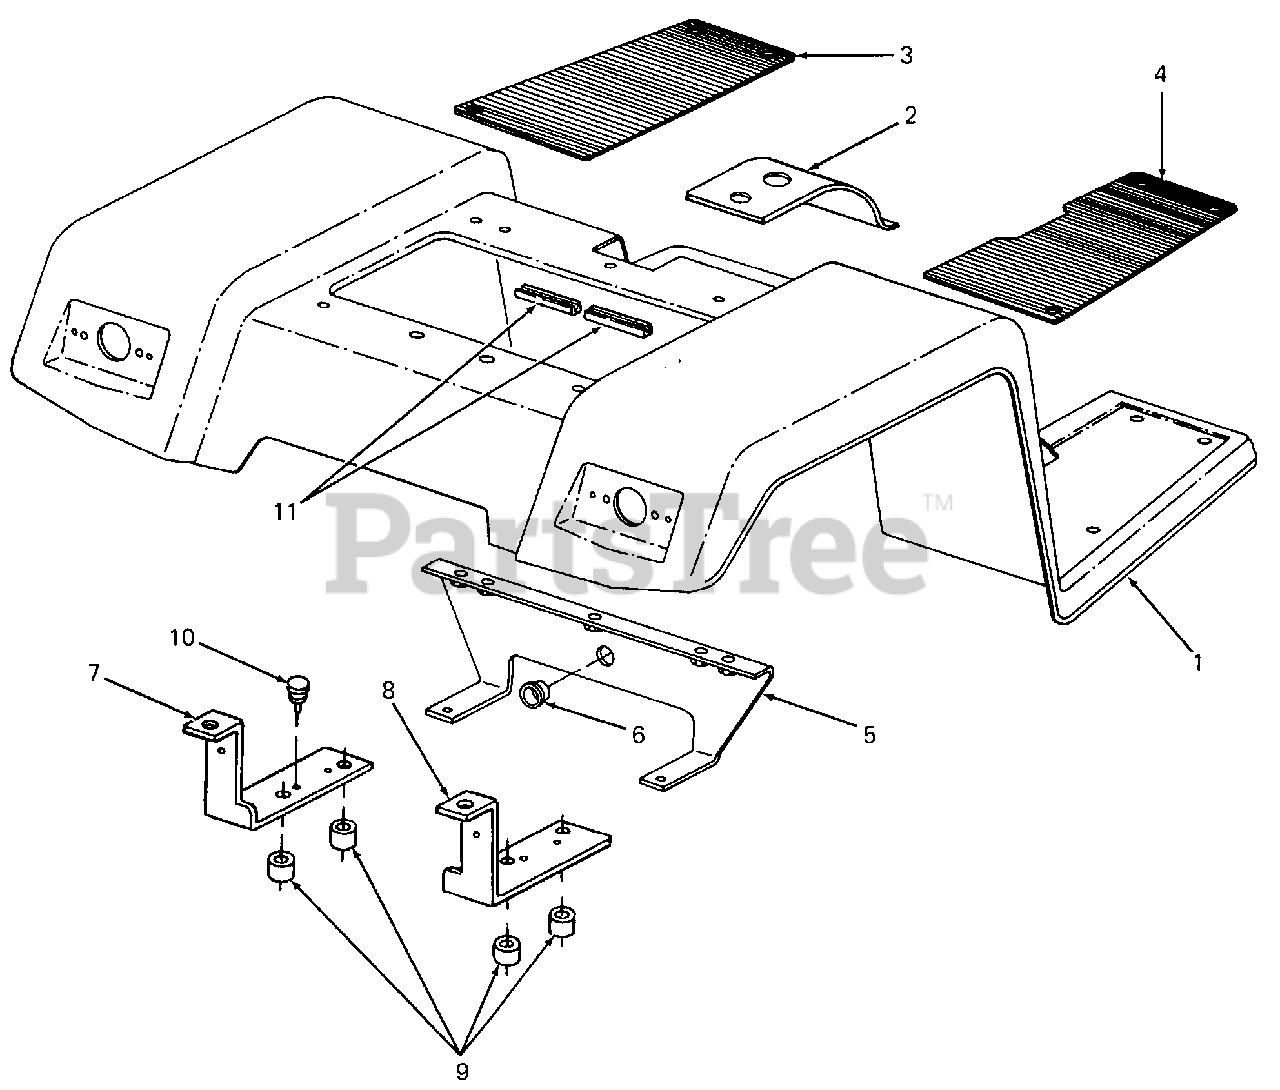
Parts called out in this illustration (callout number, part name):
2	Cover, Hydro Center w/Hole
3	Pad, LH - Foot
4	Pad, RH - Foot
5	Support, Front Fender
6	Bushing, Snap, 7/8 ID
7	Support, LH - Rear Fender
8	Support, RH - Rear Fender
9	Spacer, .39 X .88 X 1.00 Lg
10	Bumper, Rubber
11	Strip, Trim, 39.38 Lg
